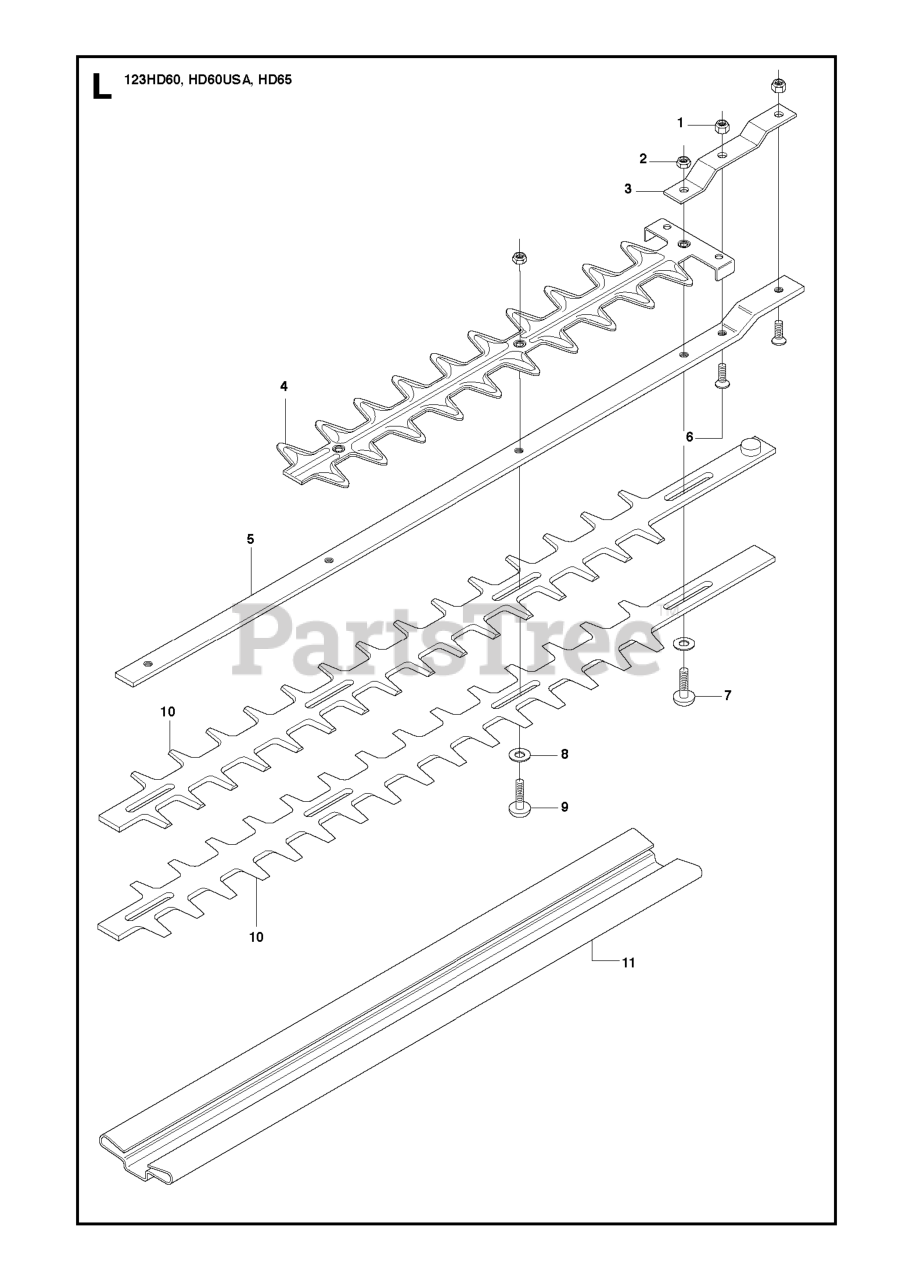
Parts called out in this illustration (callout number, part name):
4	PLATE
5	GUIDE PLATE
5	PLATE
10	BLADE
11	PROTECTOR
11	COVER
